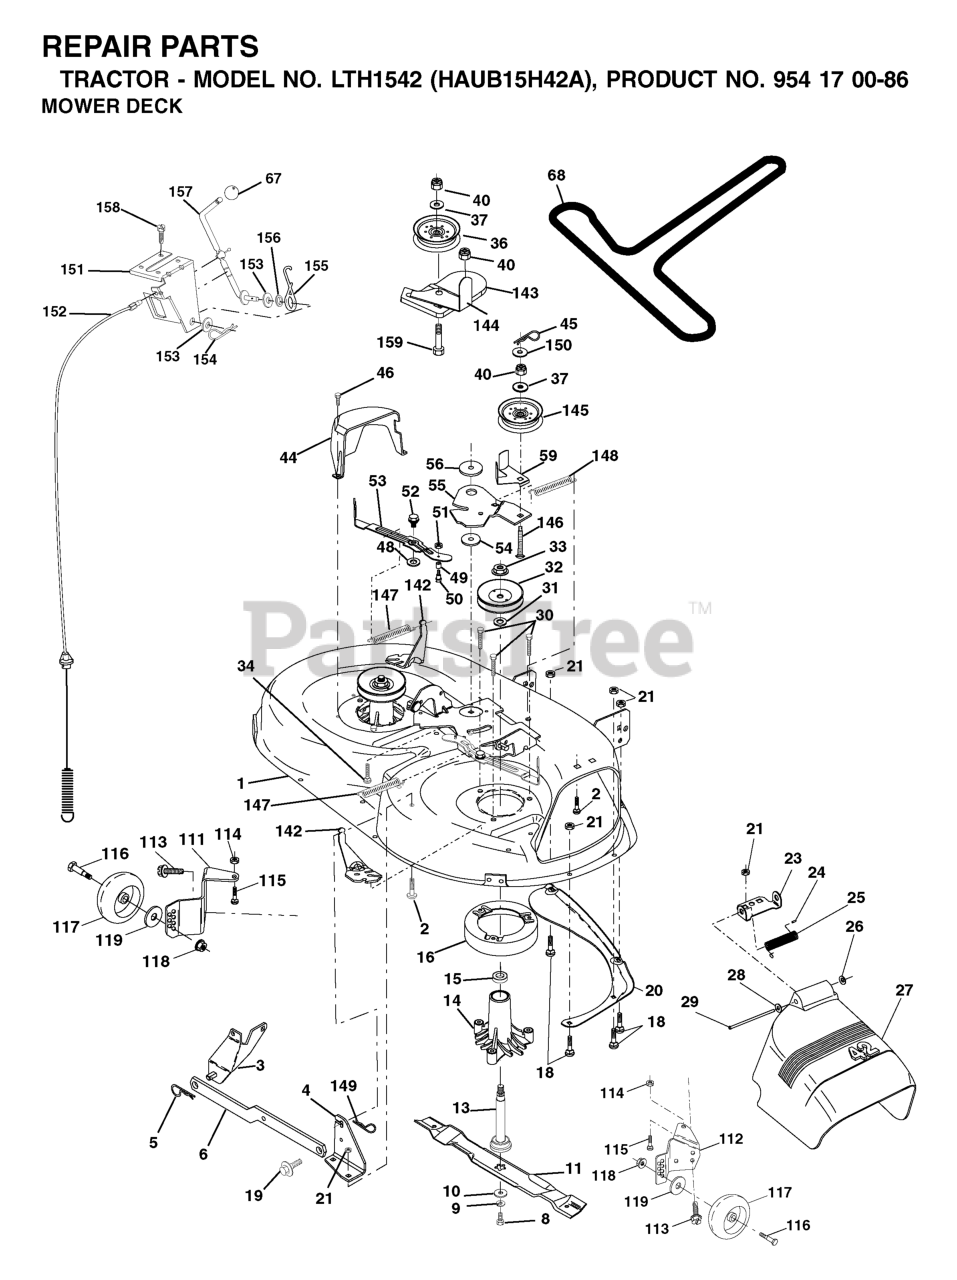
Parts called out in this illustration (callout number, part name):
1	RP.SWITCH, BLADE
2	HOUR METER
3	IGNITION SWITCH
4	KEY
5	FENDER, CONSOLE
6	CONSOLE.PLATE.BLACK
7	SCR #10-12X3/4 HEX WAS HD ZD
8	NUT 10-24 NYLOC
9	HCS #10-24 X 1/2
10	LEFT HEADLIGHT LENS
11	RT HEADLIGHT RIM GREY
12	RT HEADLIGHT REFLECTOR
13	THROTTLE CABLE
